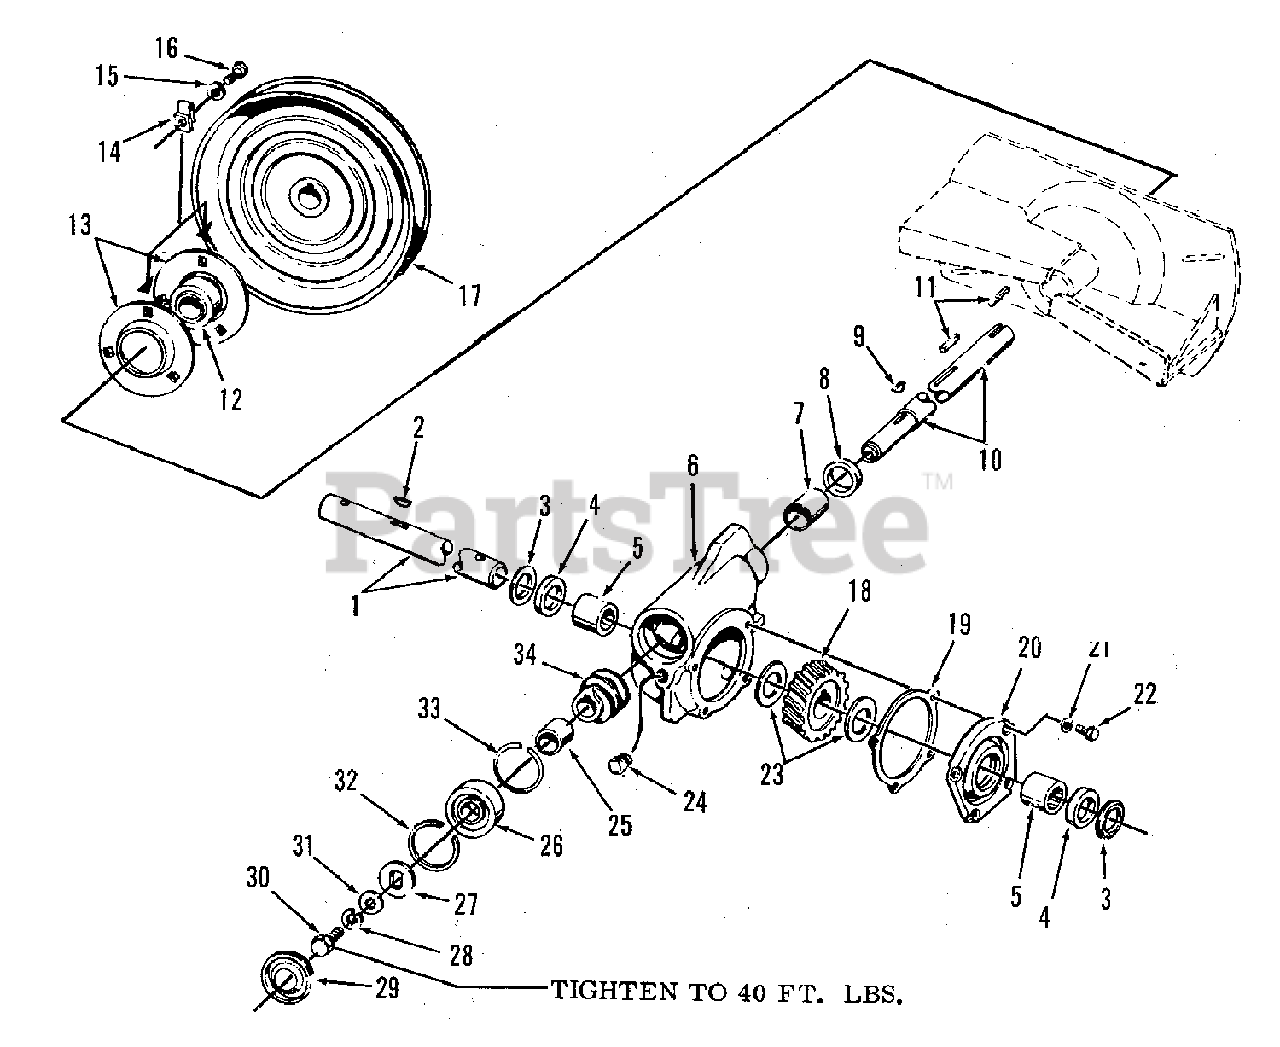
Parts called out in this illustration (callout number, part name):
1	SHAFT, Worm Gear
2	KEY, Woodruff
5	BEARING, Needle
6	HOUSING, Worm Drive
9	KEY, 3/16 x 7/8
10	SHAFT, Worm Gear
12	BEARING, Cartridge
13	BEARING, Flange
14	NUT, Retainer
15	WASHER, Lock, 5/16"
16	SCREW, Hex Cap, 5/16-18 x 3/4
21	WASHER, Lock, 1/4
22	SCREW, Hex Cap, 1/4-20 x 5/8
23	WASHER, Thrust
24	PLUG, Pipe, 3/8
26	BEARING, Ball
28	WASHER, Lock, 3/8
30	SCREW, Hex Cap, 3/8-24 x 1
31	WASHER, Flat, 5/16
32	RING, Retaining
